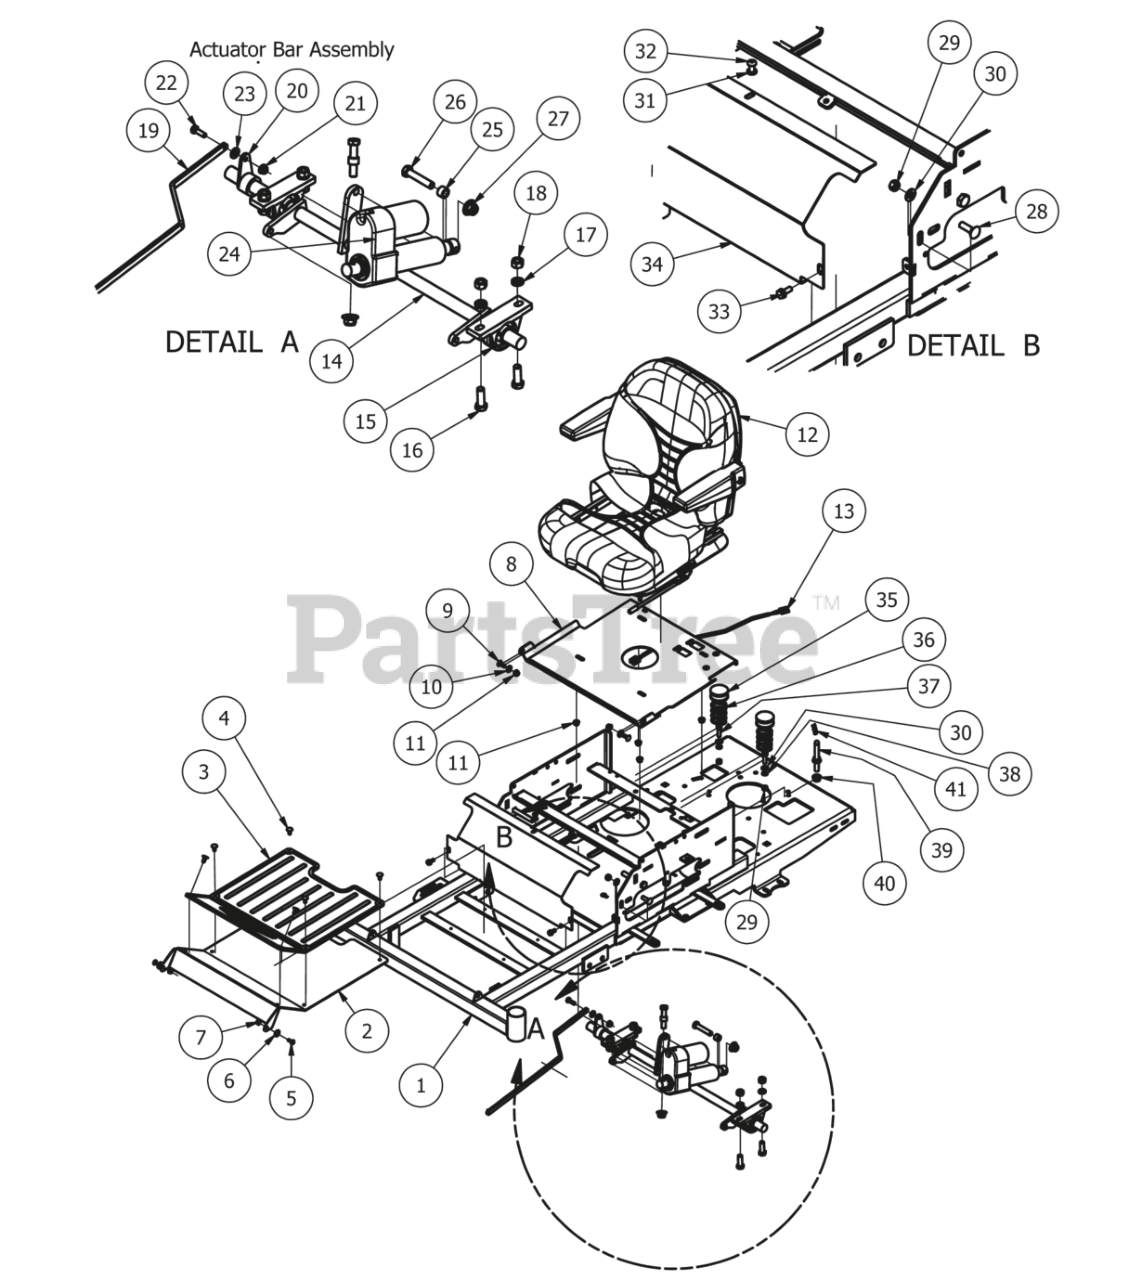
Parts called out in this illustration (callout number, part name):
2	ZT Floor Panel
3	Zt Floorboard Mat
4	Ratchet Fastener
5	1/4" x 3/4" Carriage Bolt
6	.360 ID Plastic Washer
7	1/4" Nylock Nut
8	ZT Seat Plate
9	5/16" x 7/8" Carriage Bolt
10	.360 ID Plastic Washer
11	5/16" Flange Nut Zinc W/Serrations
12	ZT/Pup Seat - WM1976
13	Seat Switch Adapter
14	Actuator Bar
15	Pillow Block Bearing
16	1/2" x 1 1/2" Hex Bolt
17	1/2" Lock Washer
18	1/2" Hex Nut
19	Height Indicator Bar
20	Height Indicator Lever
21	5/16" Flange Nut Zinc W/Serrations
22	5/16" x 1" Bolt
23	.360 ID Plastic Washer
25	1/2 x 1/2 Spacer
26	1/2-13 x 2 3/4 GR 5 Bolt
27	1/2-13 Nylon Flange Nut-Orange
28	3/8" x 1 1/4" Carriage Bolt
29	3/8" Hex Nut
30	3/8" Flat Washer
31	5/16" Lock Washer
32	5/16" x 3/4" Button Head Bolt
33	5/16 x 3/4 washer head type F screw
34	ZT Cooler Cover 2010 & Up
35	Spring Cap Cover
36	Seat Spring
37	3/8" x 1 1/4" Hex Bolt
38	3/8" Lock Washer
39	Seat Braket Pin
40	1/2" Flange Nut
41	Seat latch pin
